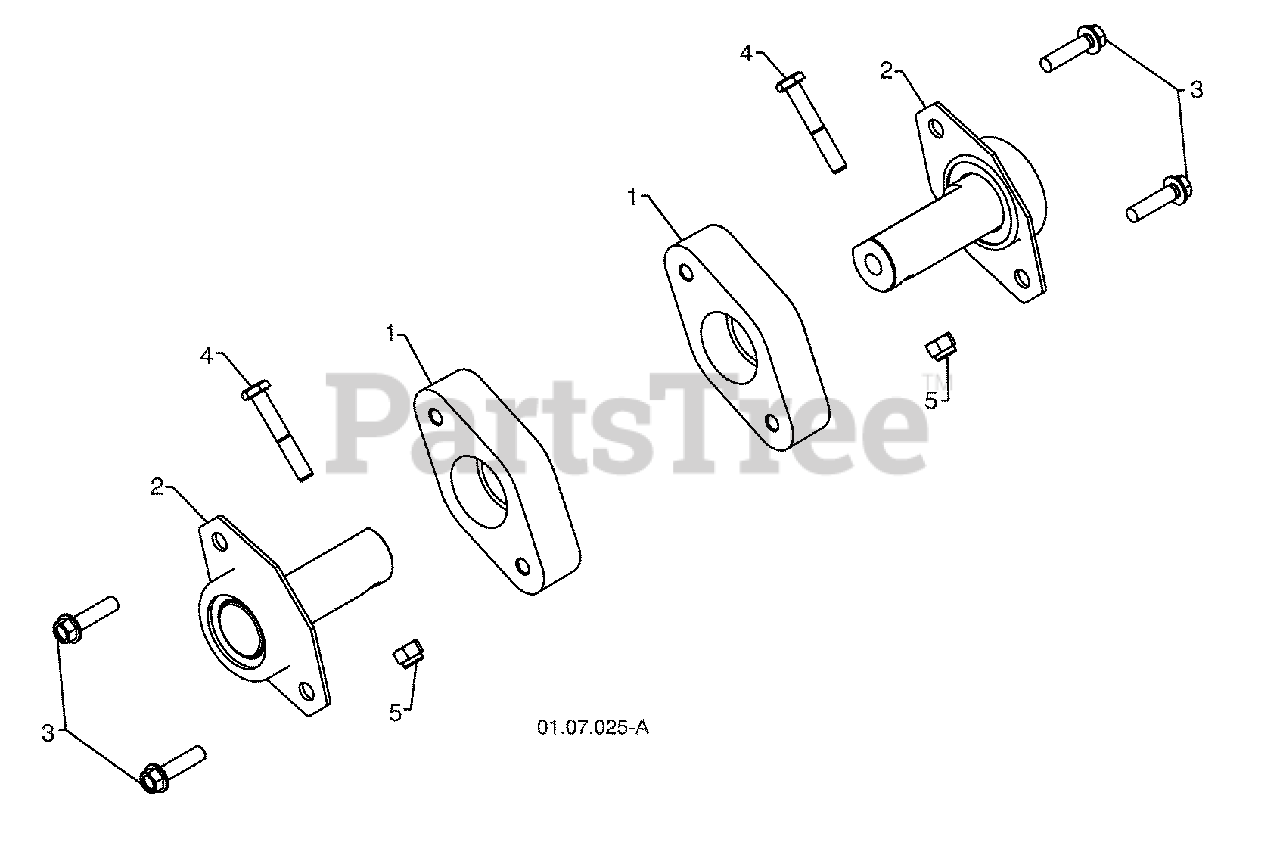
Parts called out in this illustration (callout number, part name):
1	PLASTIC RETAINER
2	AUGER BALL BEARING
3	SCREW 5/16-18 x 1.00
4	SCREW 1/4-20 x .625
5	NUT 1/4-20
